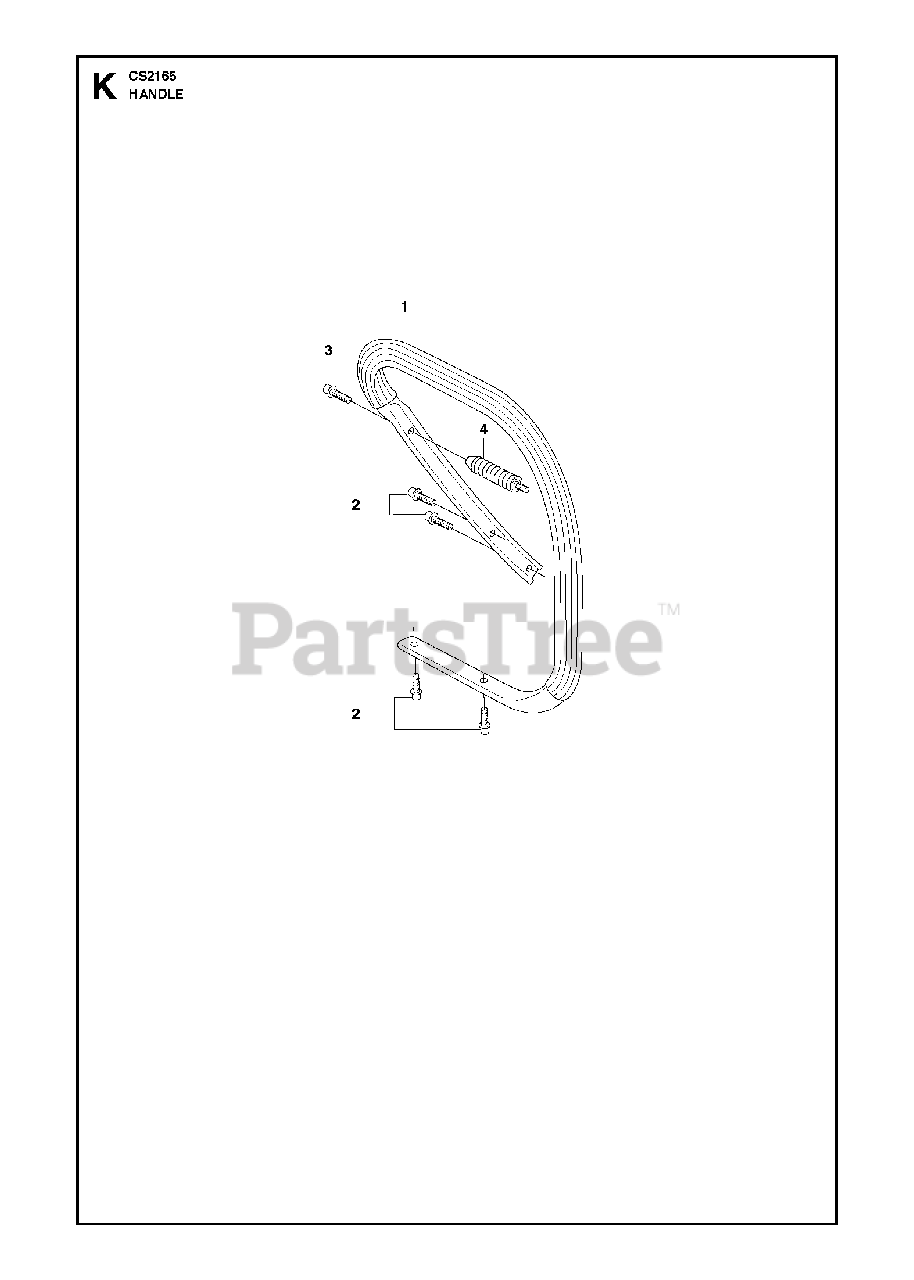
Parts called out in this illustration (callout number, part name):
1	FRONT HANDLE
2	SCREW
4	ANTIVIBE MOUNT
4	VIBRATION ABSORBER
